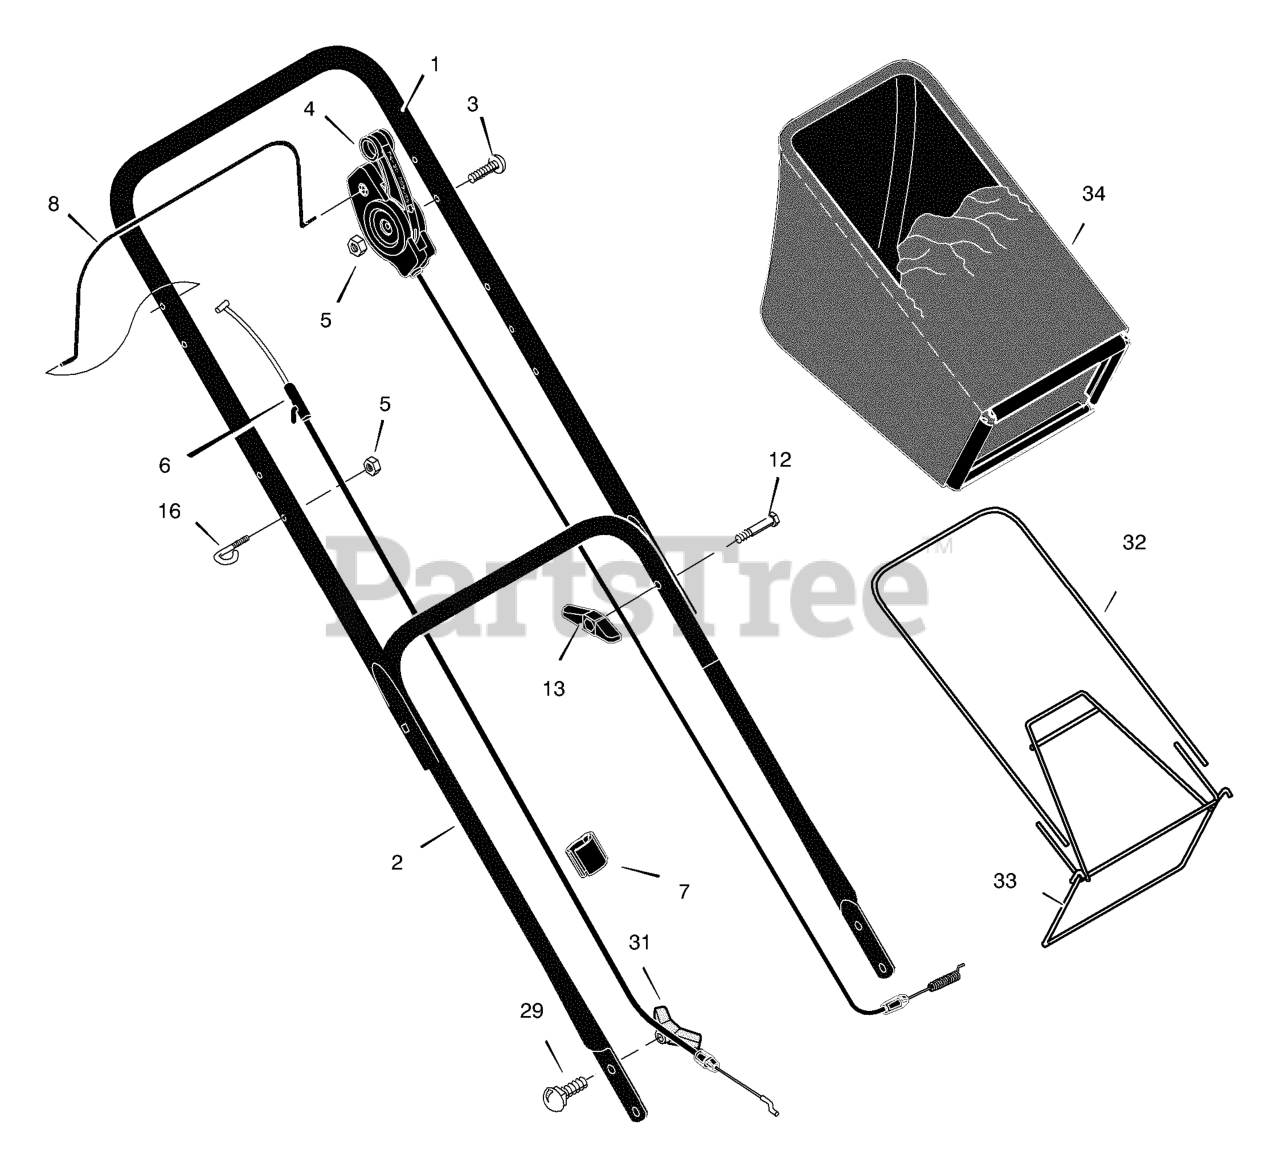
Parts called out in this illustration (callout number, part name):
1	Handle, Upper (Black)
2	Handle, Lower (Black)
4	Control, Drive
5	Locknut
6	Cable, Stop (Briggs)
7	Fastener, Double Cable
8	Lever, Stop
13	Knob
16	Guide, Rope
29	Bolt, Carriage
31	Knob, Plastic
32	Tube, Bag
33	Frame Assembly
34	Bag, Cloth
